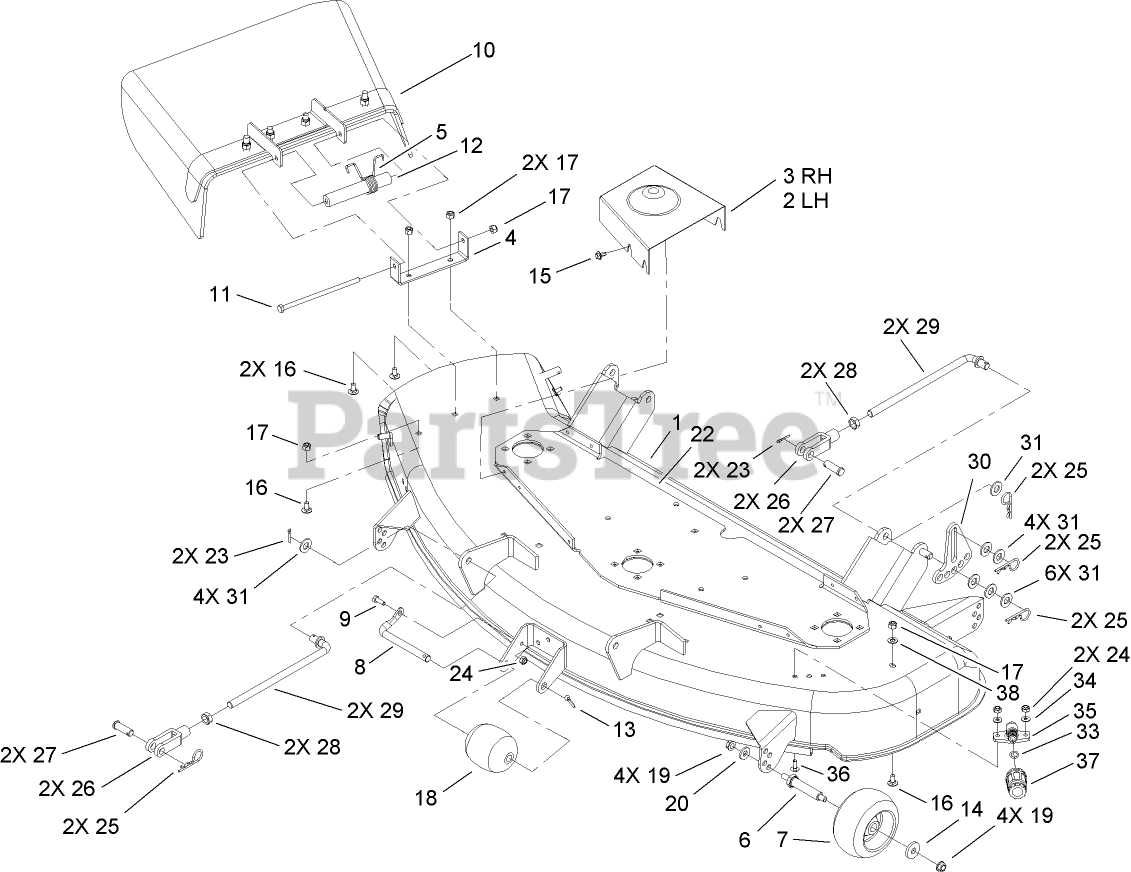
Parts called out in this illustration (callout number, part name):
3	COVER-BELT, RH
4	BRACKET-PIVOT
5	SPRING-TORSION
7	ROLLER-SCALP, ANTI
8	ROLLER-SHAFT
9	SCREW-HH
10	DEFLECTOR ASM
11	BOLT-HH
12	SPACER-DEFLECTOR
13	PIN-COTTER
14	WASHER
15	SCREW-HHFTF
16	SCREW-CARR
17	NUT-LOCK, NI
18	ROLLER
19	NUT-HHF, WHIZ
20	WASHER-BELLEVILLE
22	PLATE-REINFORCEMENT, DECK
23	PIN-COTTER
24	NUT-LOCK, NI
25	PIN-COTTER
26	CLEVIS
27	PIN-CLEVIS
28	NUT-JAM
30	LINK-HOC, ADJUSTING
31	WASHER-FLAT
33	O-RING
34	WASHER-FLAT
36	BOLT-CARR
37	CONNECTOR-HOSE
38	WASHER-PLAIN
